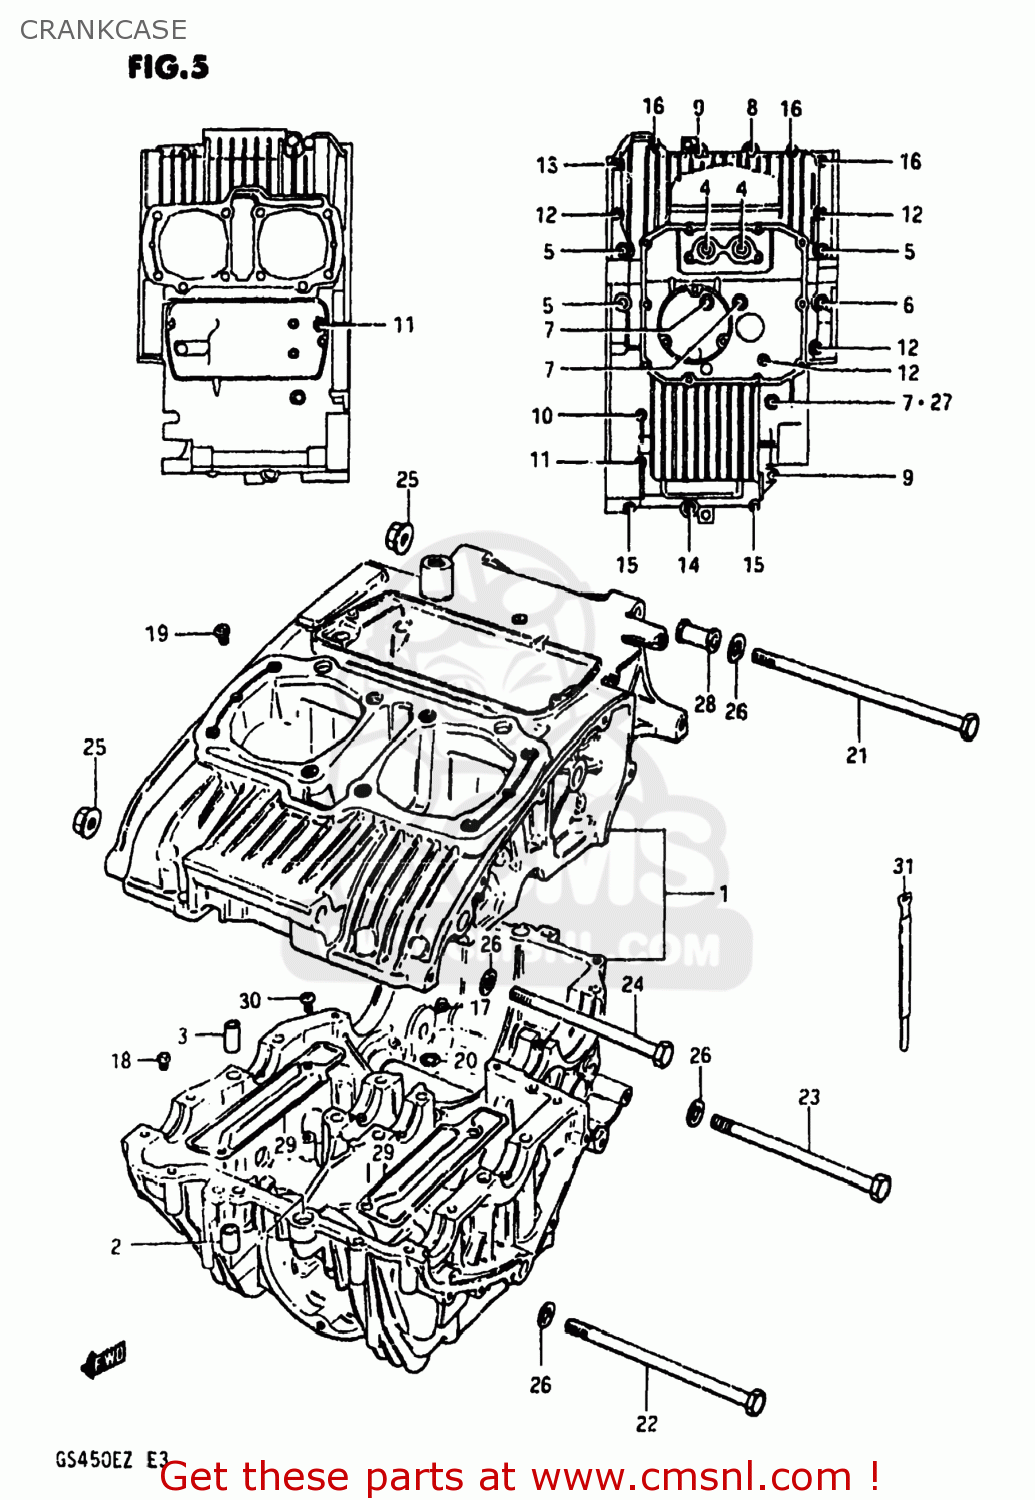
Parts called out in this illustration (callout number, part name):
1	CRANKCASE SET
2	PIN(10.4X13X22)
3	PIN (11X20)(SUS)
4	BOLT
5	BOLT
6	BOLT
7	BOLT
8	BOLT 8X65
9	BOLT (8X45)
10	BOLT
11	BOLT
12	BOLT (6X90)
13	BOLT (6X70)
14	BOLT 6X65
15	BOLT ,6X50
16	BOLT,UNDER
17	JET
18	JET
19	JET
20	O RING(D:1.05,ID:3.1)
21	BOLT 10X250
22	BOLT(10X210)
23	BOLT 10X160
24	BOLT
25	NUT 10MM
26	WASHER
27	GASKET 8.2X14X1 (NAS)
28	SPACER,ENGINE MOUNT
29	PLATE,OIL SEPARATOR
30	SCREW
31	CLAMP
